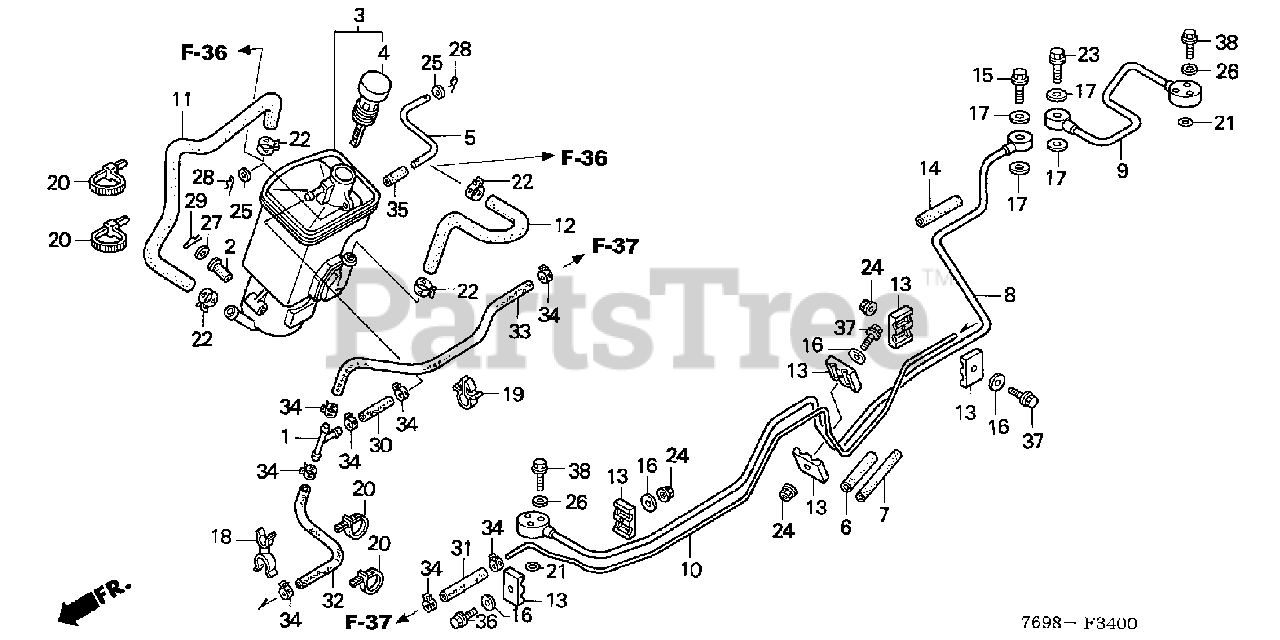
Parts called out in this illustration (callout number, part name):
1	JOINT, BREATHER THREE-WAY
2	RUBBER, FUEL TANK PIVOT
3	TANK ASSY., OIL
4	CAP, OIL TANK
5	BRACKET A, OIL TANK
6	TUBE (12X80)
7	TUBE (8X100)
8	PIPE A, FEED
9	PIPE, FEED (B)
10	PIPE A, BREATHER
11	TUBE, SUCTION
12	TUBE, RETURN
13	SADDLE, PIPING
14	TUBE (11.9X50)
15	BOLT A, JOINT
16	WASHER (6.5X25X1.5)
17	WASHER, JOINT (14MM)
18	CLIP, CABLE
19	CLIP, WIRE HARNESS
20	BAND, CABLE (120MM) (BLACK)
21	O-RING (11.8X1.9)
22	CLAMP D (19MM)
23	BOLT A, JOINT
23	BOLT, DRAIN PLUG (14MM)
24	NUT, FLANGE (6MM)
25	WASHER, PLAIN (5MM)
26	WASHER, PLAIN (6MM)
27	WASHER, PLAIN (8MM)
28	PIN, LOCK (5MM)
29	PIN, LOCK (8MM)
30	BULK HOSE, FUEL (7.5X3000)
31	BULK HOSE, FUEL (7.5X3000) (7.3X60)
32	BULK HOSE, FUEL (7.5X3000) (7.3X500)
33	BULK HOSE, FUEL (7.5X3000)
34	CLIP, TUBE (D12.5)
35	BULK HOSE, VACUUM (5X3000) (5X22)
36	BOLT, FLANGE (6X28)
37	BOLT, FLANGE (6X32)
38	BOLT, FLANGE (6X35)
